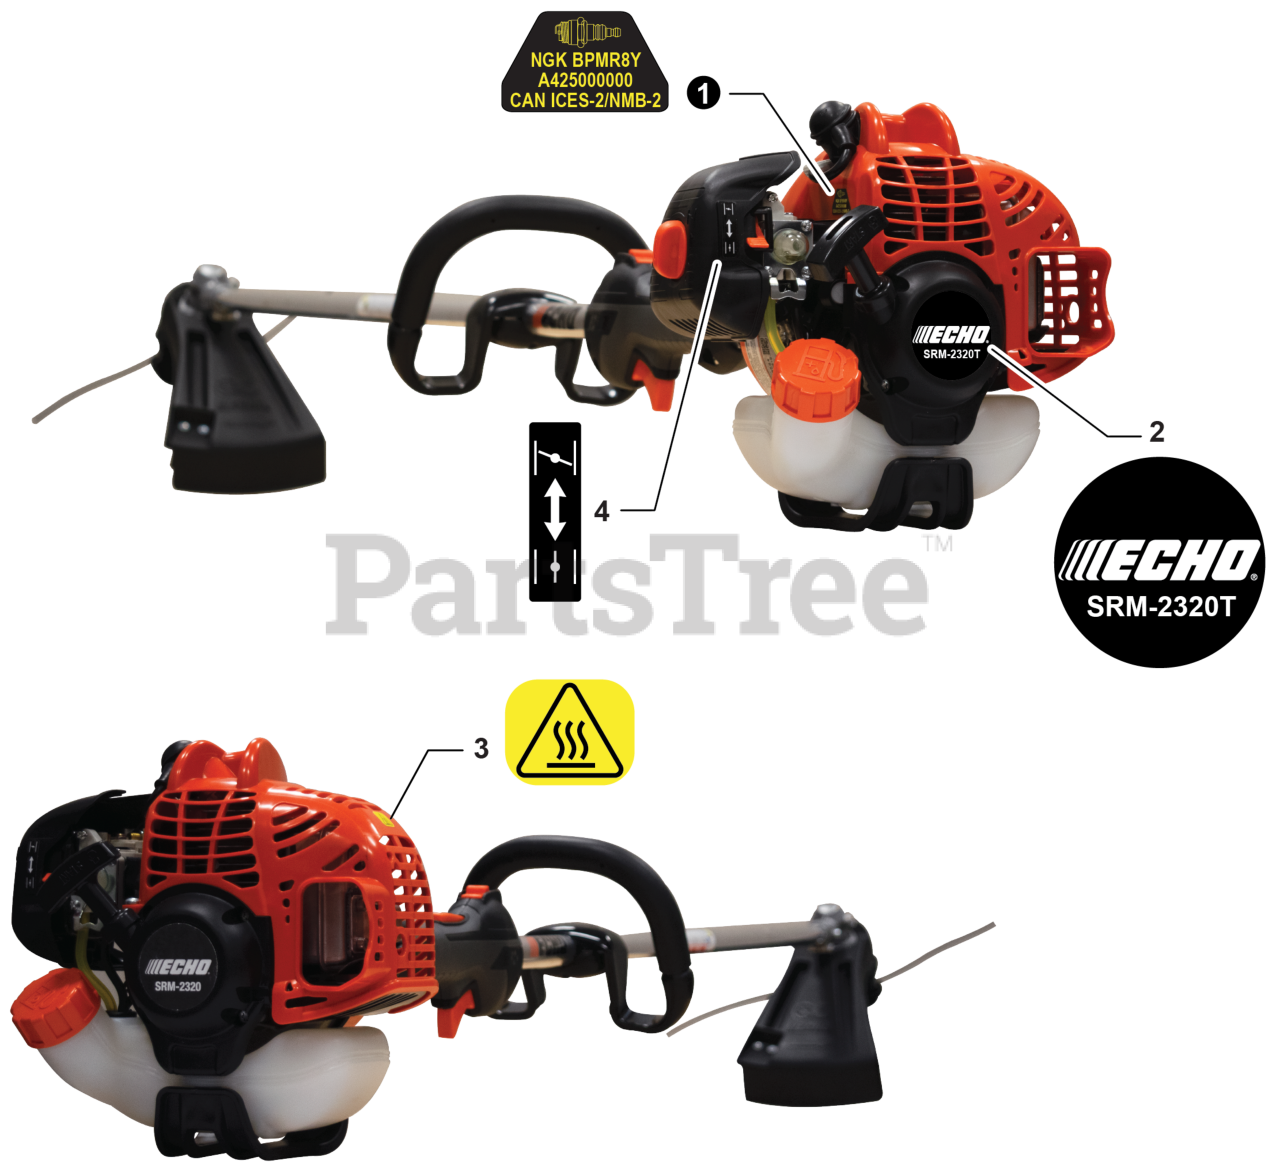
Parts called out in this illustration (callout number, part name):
1	LABEL - SPARK PLUG - BPMR8Y
2	LABEL - RECOIL STARTER - SRM-2320T
3	LABEL - CAUTION - HOT
4	LABEL - CHOKE
